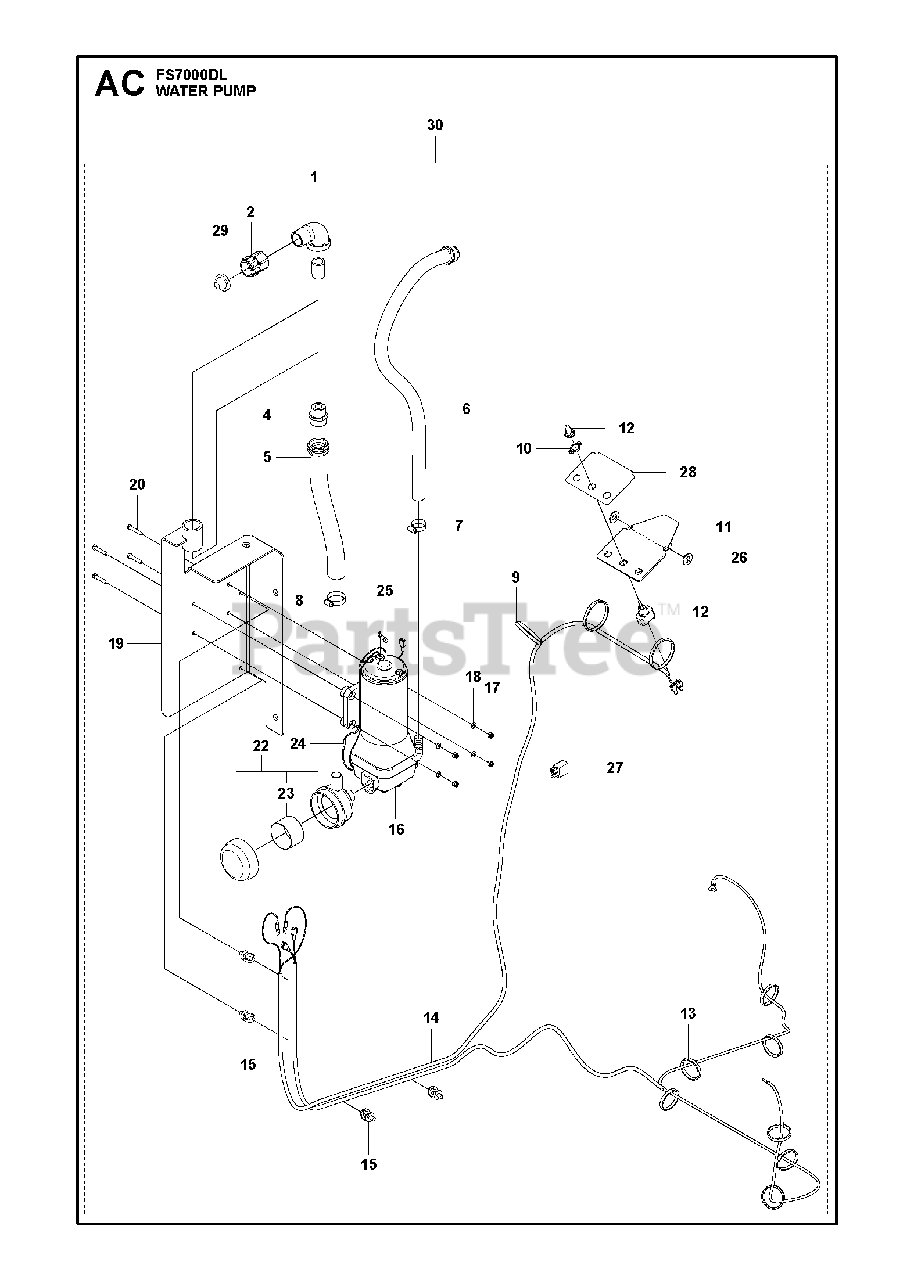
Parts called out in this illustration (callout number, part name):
17	HEXAGON LOCKING NUT
18	WASHER
23	STRAINER SCREEN. W/P INLET FILTER
25	TERM., MALE DISCONNECT, 1/4"
26	WASHER
